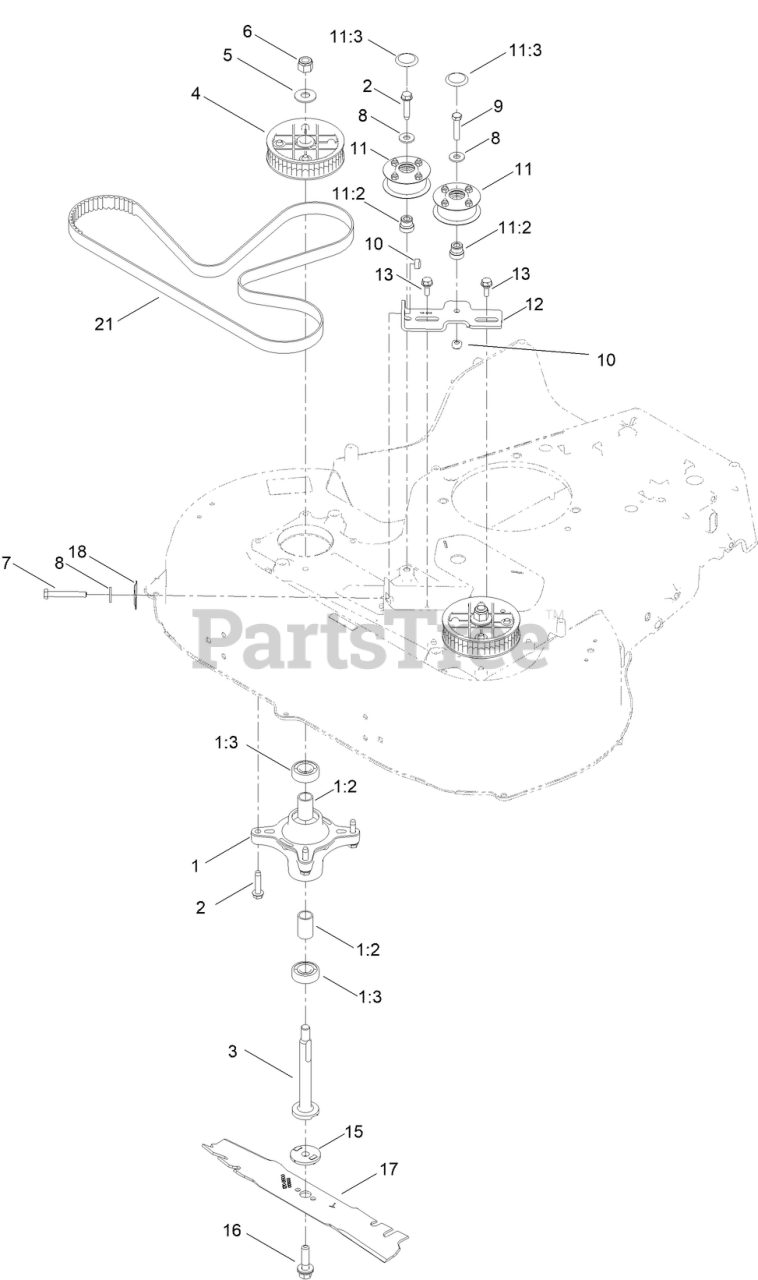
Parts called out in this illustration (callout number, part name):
1	SPINDLE ASM
1:2	SPACER
1:3	BEARING-BALL
2	SCREW-THD ROLL, HWH
3	SHAFT-SPINDLE
4	SPROCKET
5	WASHER-SPRING
6	NUT-HEX
7	BOLT-HH FT
8	WASHER-FLAT
9	SCREW-HH
10	NUT-HEX
11	PULLEY KIT
11:2	ADAPTER-BORE
11:3	PLUG-CAP
12	BRACKET-IDLER
15	ADAPTER-BLADE
16	BOLT-BLADE
17	BLADE-ROTARY [BLACK]
18	SPRING-FLAT
21	BELT-SYNCHRONOUS
